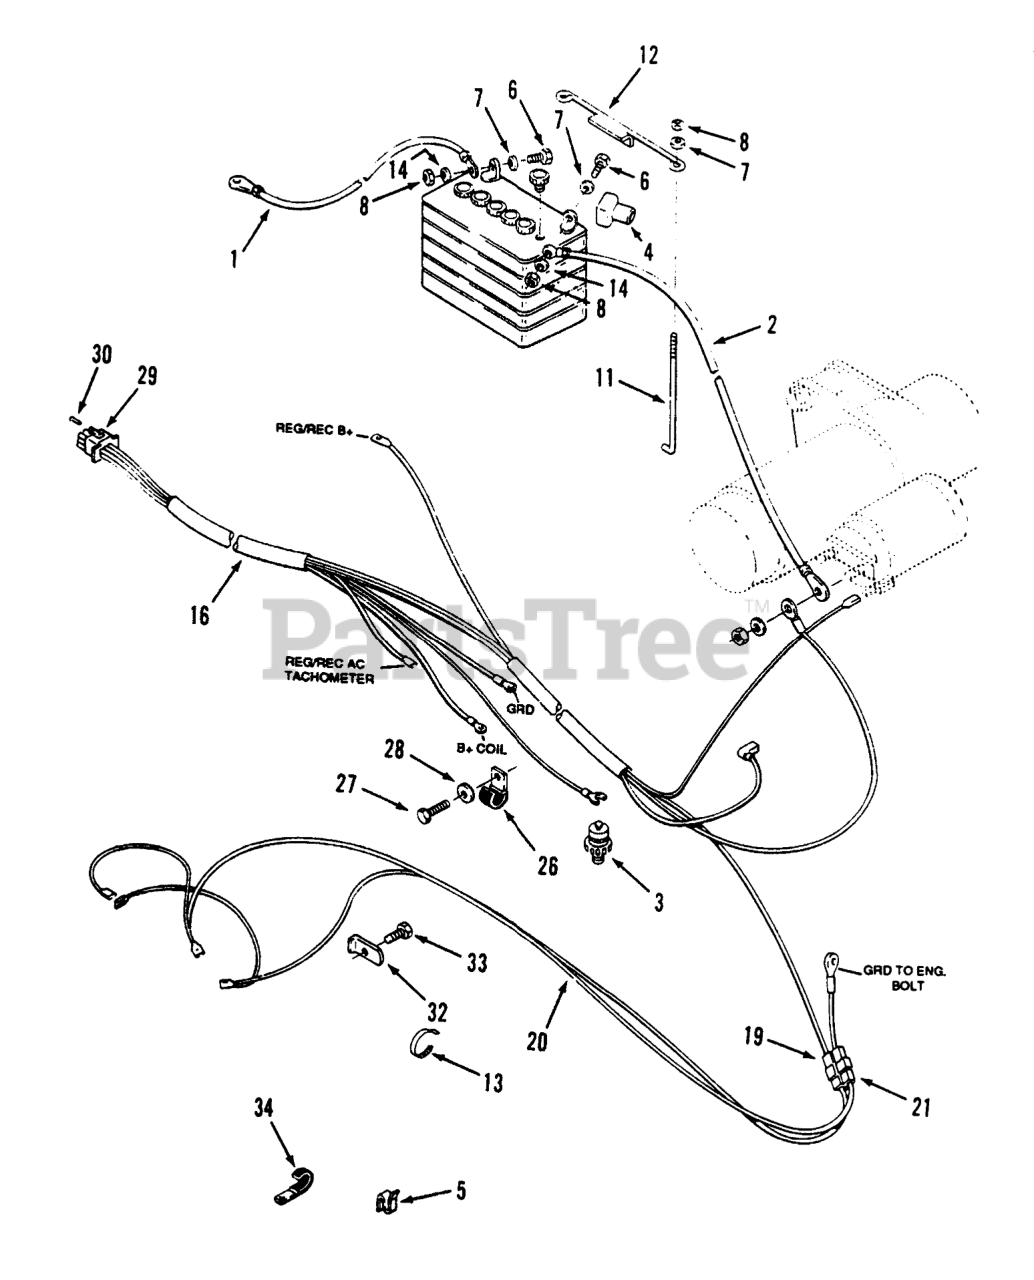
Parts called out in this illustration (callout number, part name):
1	ASS'Y-WIRE
2	SHIELD-SD DISCHARGE
3	SWITCH
4	Boot
5	SPEED CLIP
6	SCREW-HH
7	WASHER-FLAT
8	Nut
11	HOOK-BATTERY RETAIN
12	HOLDDOWN-BATTERY
13	PLASTIC TIE
16	Engine Wiring Harness
19	MALE CONNECTOR
20	HARNESS-HEADLIGHT
21	CONNECTOR BODY
26	Clip
27	Bolt
28	LOCKWASHER 1/4 IT
29	CONNECTOR CAP
30	CONTACT SOCKET
32	LOCK-HEADLIGHT
33	Bolt
34	CLIP
